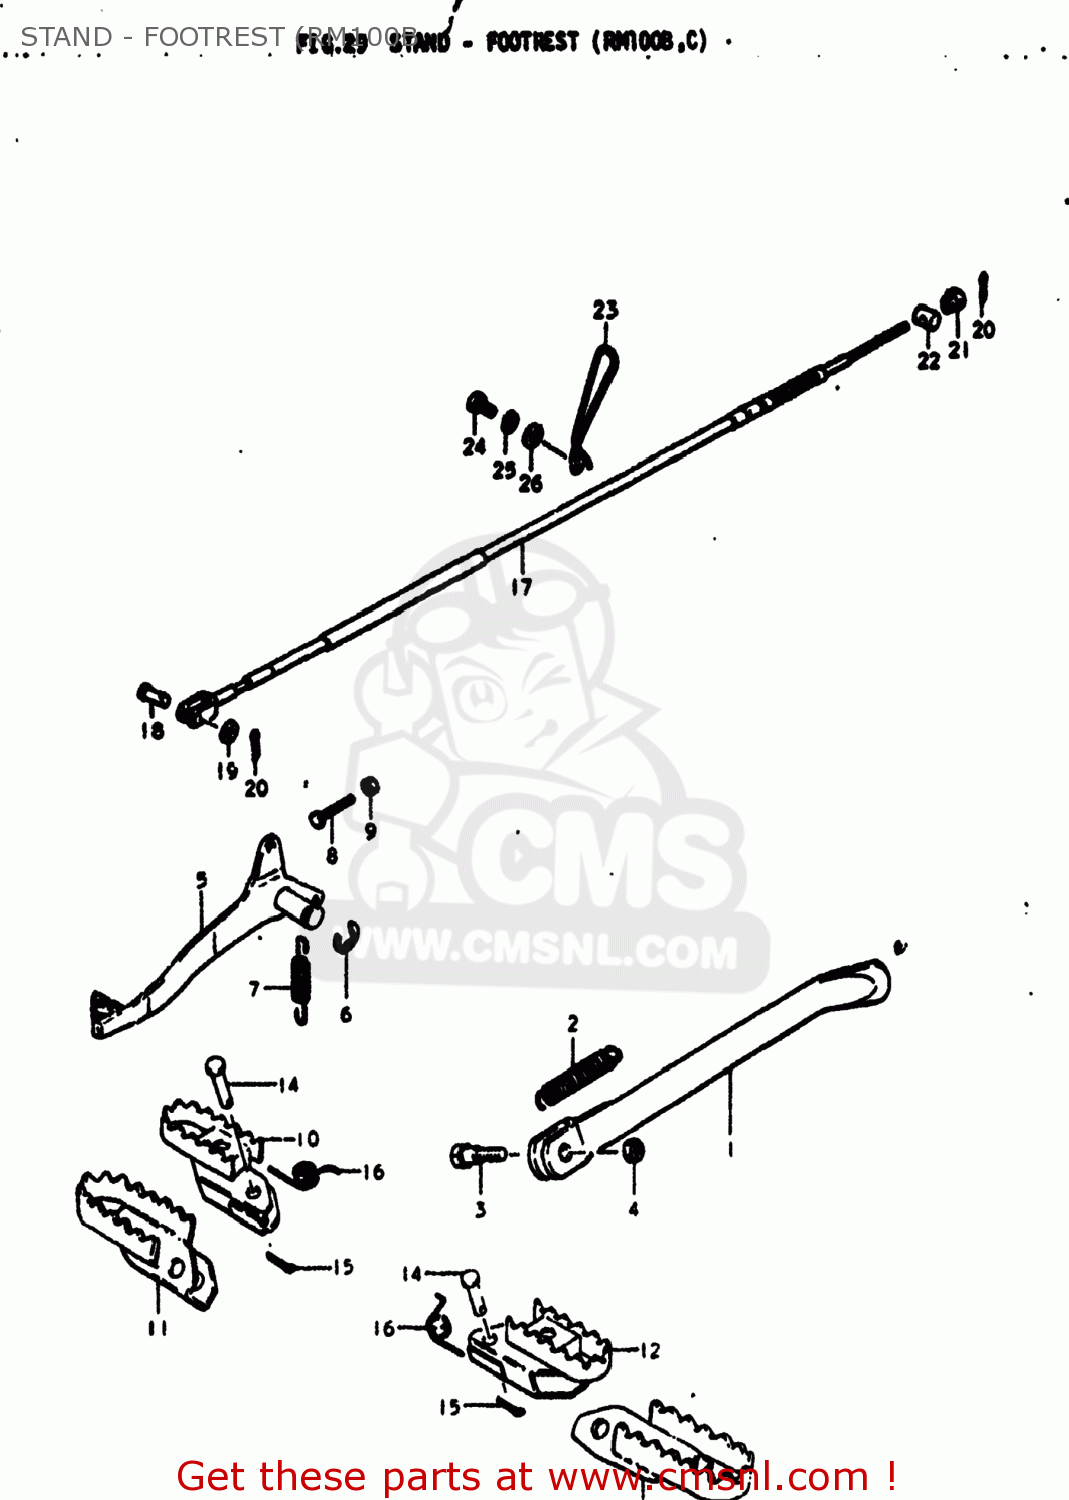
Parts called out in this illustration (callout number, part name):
1	STAND,SIDE
2	SPRING
3	BOLT(10X30)
4	NUT
5	PEDAL,BRAKE
6	E RING
7	SPRING
8	BOLT(6X25)
9	NUT
10	BAR,FOOTREST,RIGHT
11	FOOTREST,FR,R
12	FOOTREST
13	FOOTREST,FR,L
14	PIN
15	PIN 20X20
16	SPRING
17	CABLE,RR BRAKE
18	PIN(L:17.5)
19	WASHER
20	PIN
21	NUT
22	PIN(11X18)
23	GUIDE,CABLE
24	BOLT
25	LOCK WASHER
26	WASHER
